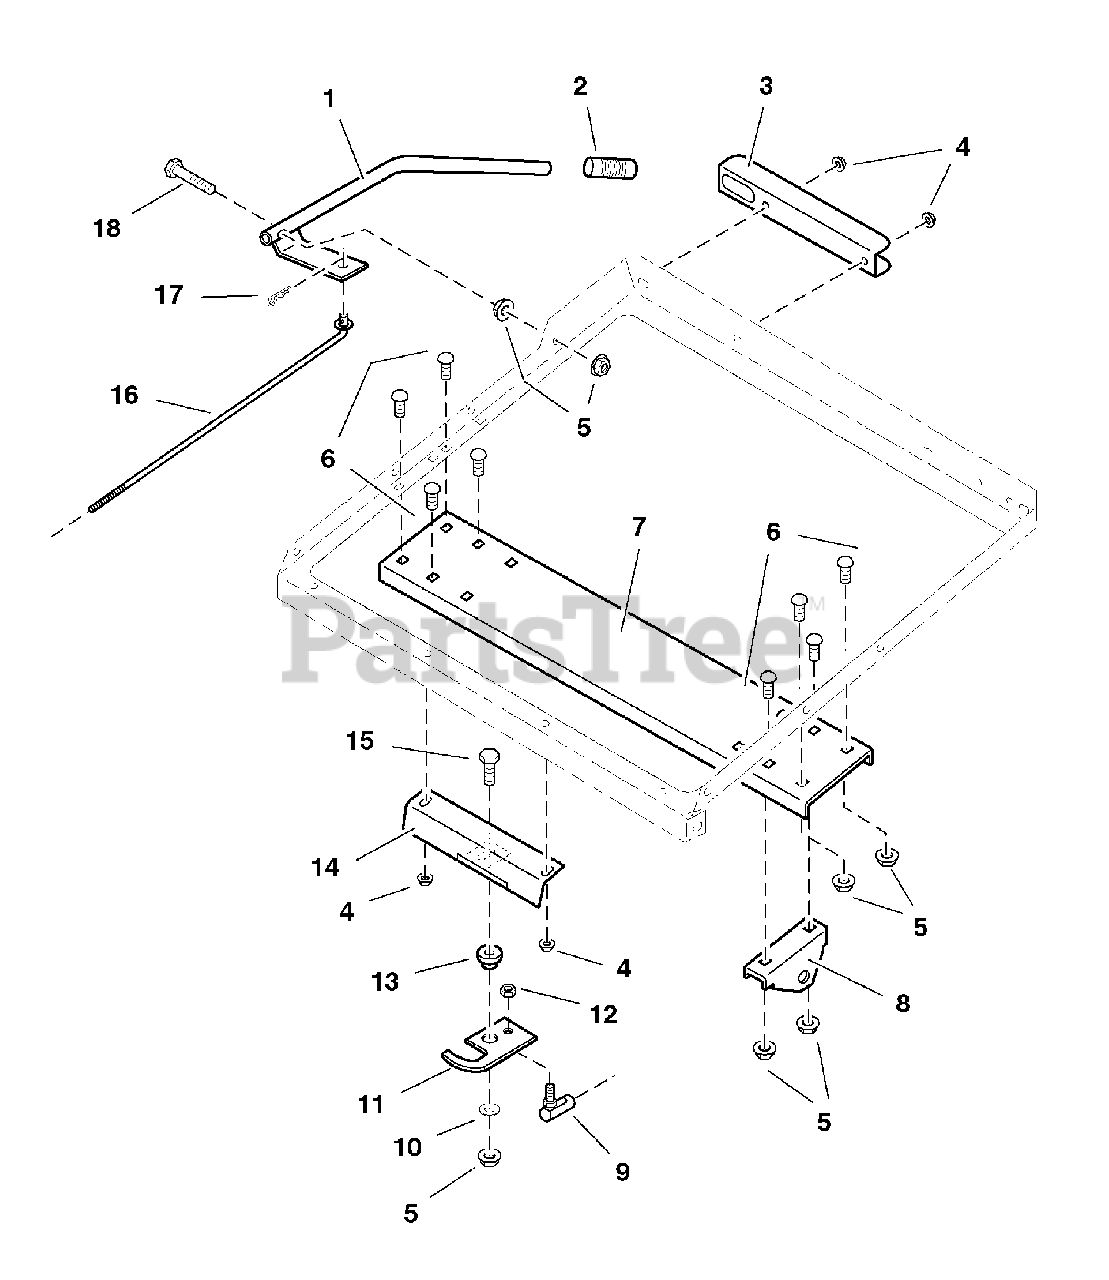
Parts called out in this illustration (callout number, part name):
1	BOX HANDLE
3	HANDLE MOUNT BRACKET
4	NUT, Hex, Flange, 1/4-20
5	NUT, 3/8-16 Hex Serrated Flange
6	CARRIAGE BOLT, 3/8-16 x 1-1/2
7	BASE FRAME PIVOT MOUNT
8	PIVOT BRACKET
9	BALL JOINT
10	WASHER, 3/8 SAE
11	LATCH HOOK
12	NUT, Hex
13	LATCH HOOK HUB
14	LATCH HOOK PIVOT PLATE
15	CAPSCREW, Hex Hd, 3/8-16 x 1
16	LATCH ROD
17	HAIRPIN CLIP
18	BOLT, 3/8-16 X 2, GD5, CZ
